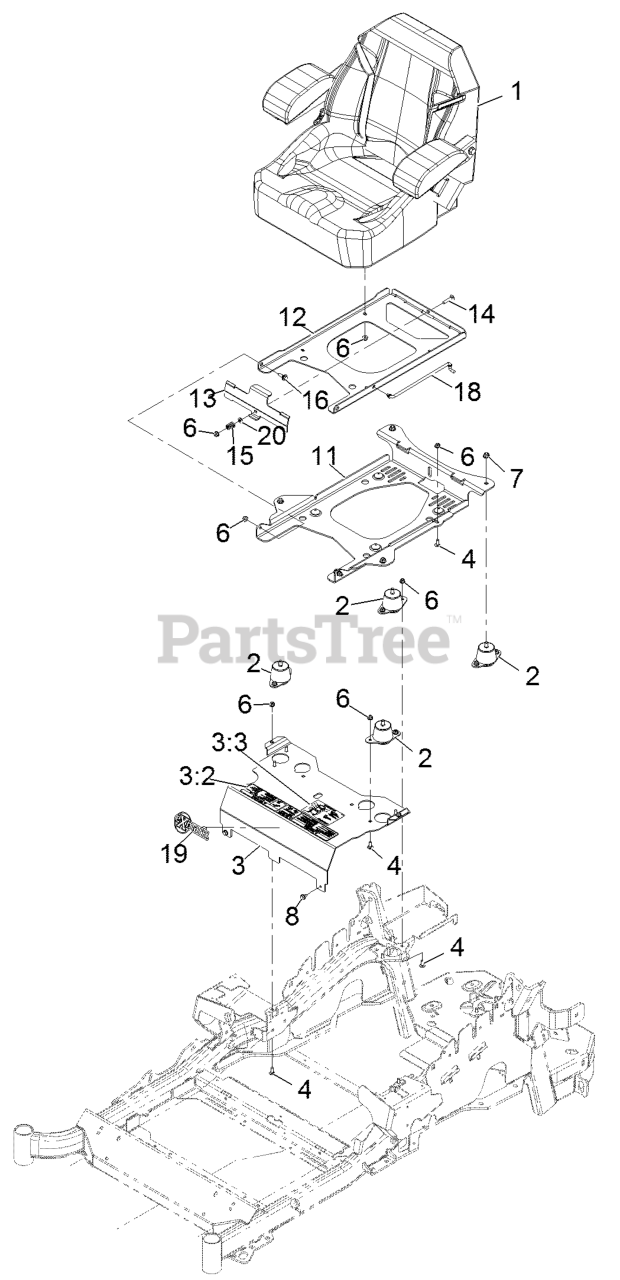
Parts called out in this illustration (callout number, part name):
2	ISOLATOR-SEAT
3	MOUNT-SEAT
3:2	DECAL-CONSOLE
3:3	DECAL-SERVICE AID
4	SCREW-CARR
6	NUT-HF, NI
7	NUT-HF, NI
11	PLATE-TILT, SEAT SUPPORT
12	PLATE-FRAME, SEAT
13	PLATE-LATCH, SEAT
14	BOLT-CARR
15	SPRING-COMPRESSION
16	SCREW-SHOULDER
18	ROD-PROP
20	WASHER-PLAIN
